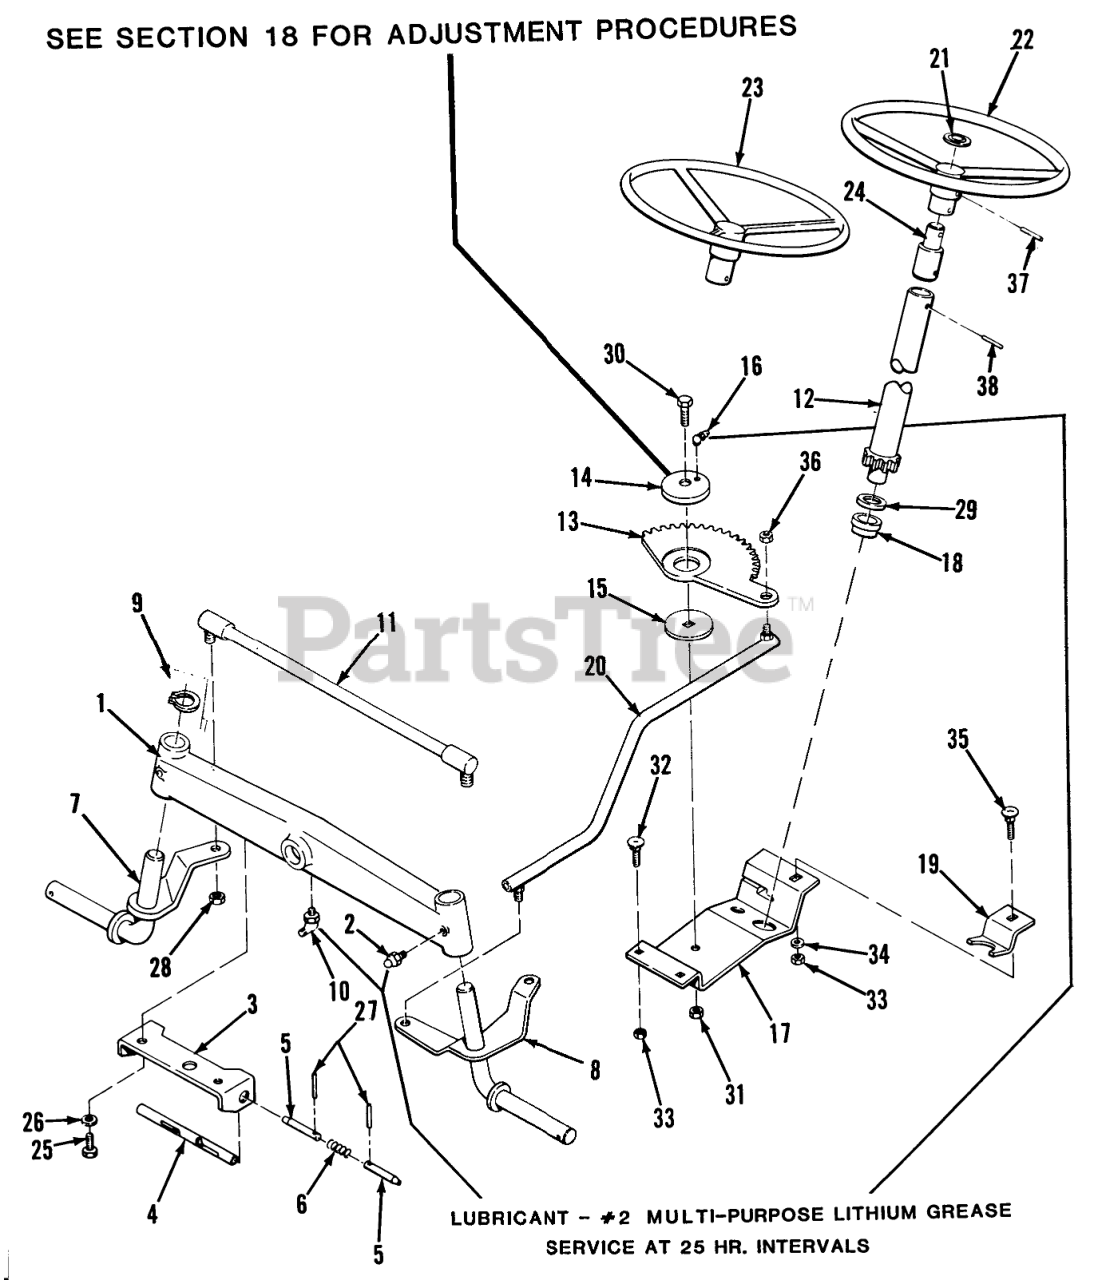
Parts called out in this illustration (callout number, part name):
1	Axle-Front
2	Zerk
3	Support Bracket
6	SPRING
7	ASSY ARM STEERING R
8	ASSY ARM STEERING R
9	Snap Ring
10	FITTING-GREASE
11	ASSY TIE ROD R
12	ASSY PINION & SHA B
13	GEAR SECTOR
14	BUSHING
15	WASHER-BEARING
16	Fitting-Grease
17	Steering Gear Bracket
18	BEARING-WHEEL
19	RETAINER R (NS)
20	ASSY BALL JOINT L R
21	STEERING WHEEL INSE
22	Steering Wheel-13" Soft 211-5 Only
23	WHEEL STEERING
24	SHAFT COUPLER
25	HHCS
26	Lockwasher
27	SPIROL PIN
28	Nut-Lock
29	WASHER
30	Bolt
31	NUT
32	Bolt
33	Nut
34	WASHER 5/16 SAE
35	Bolt-Carriage
36	NUT-6
37	SPIROL PIN 5/16X13/8
38	Pin-Roll
